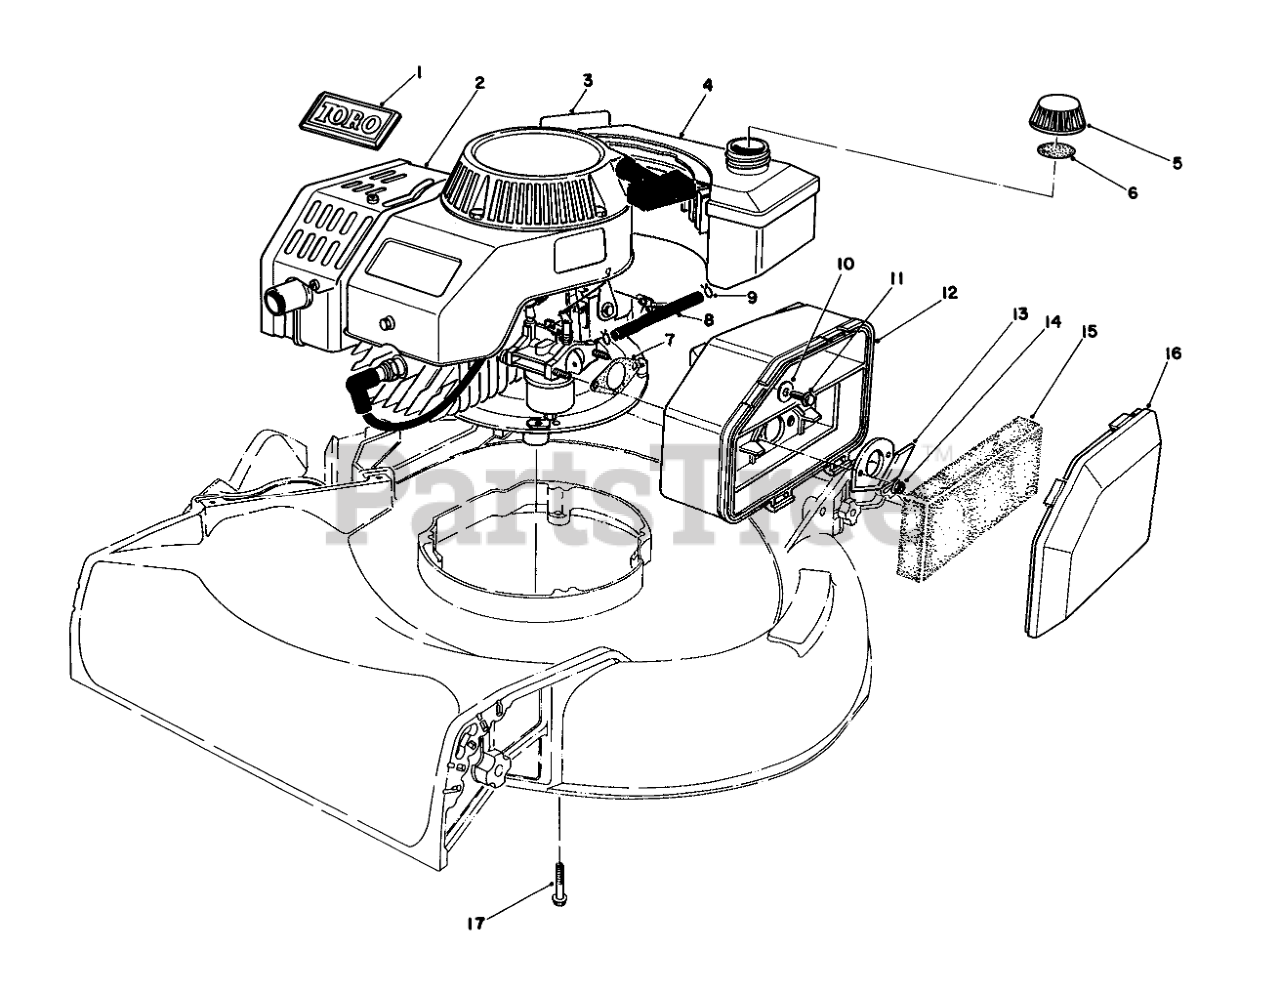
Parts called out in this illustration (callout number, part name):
1	TORO LOGO PLT
2	Engine
3	Decal-Maintenance
4	Fuel Tank Assembly
5	Gas Cap Assembly (Incl. Ref. #6)
6	Gasket
7	GASKET-AIR CLEANER
8	FUEL LINE
9	CLAMP-HOSE
10	WASHER-FLAT
11	SCREW-HH
12	AIR CLEANER
13	SPIT BACK DEFLECTOR
14	NUT-LOCK
15	FILTER
16	AIR CLEANER COVER
17	FLG SCREW,3/8-16X2.000
